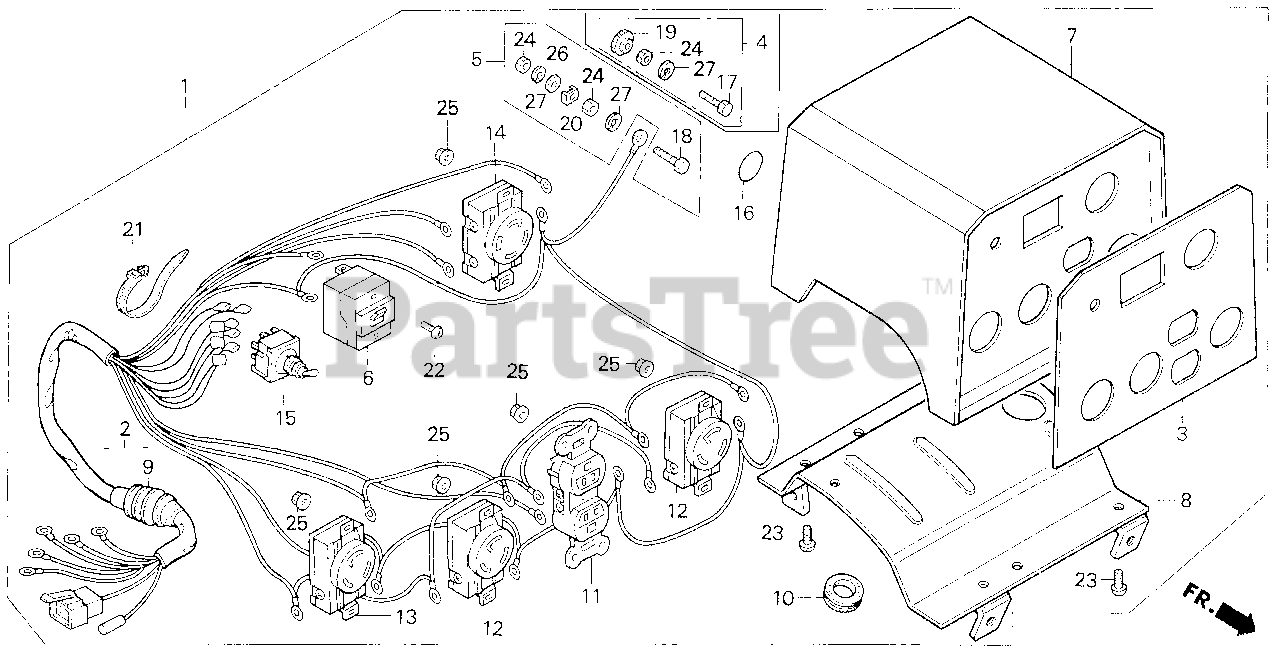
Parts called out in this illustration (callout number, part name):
1	BOX ASSY., CONTROL *R8* (BRIGHT RED)
2	WIRE HARNESS ASSY.
3	MARK, SWITCH PANEL (NOT AVAILABLE)
3	PLATE, CONTROL INDICATION (NOT AVAILABLE)
4	TERMINAL SET, GROUND
5	TERMINAL SET, GROUND
6	BREAKER, CIRCUIT (13A)
7	BOX, CONTROL *R280* (POWER RED)
8	PLATE (LOWER) *NH105* (MAT BLACK)
9	GROMMET, A.C. WIRE
10	GROMMET, MAIN WIRE
11	RECEPTACLE (20A/125V) (MATSUSHITA)
12	RECEPTACLE (20A/125V) (NOT AVAILABLE)
13	RECEPTACLE (3-PRONG) (30A/125V)
14	RECEPTACLE (20A-125/250V) (MATSUSHITA) (NOT AVAILABLE)
15	SWITCH ASSY., VOLT CHANGE
16	MARK, GROUND
17	BOLT, HEX. (6X22)
18	BOLT, HEX. (6X28)
19	NUT, SPECIAL (6MM)
20	RETAINER (6MM)
21	TIE, CABLE (NATURAL 225X5.0)
22	SCREW, PAN (4X6)
23	SCREW, PAN (6X10)
24	NUT, HEX. (6MM)
25	NUT, FLANGE (4MM)
26	WASHER, PLAIN (6MM)
27	WASHER, SPRING (6MM)
